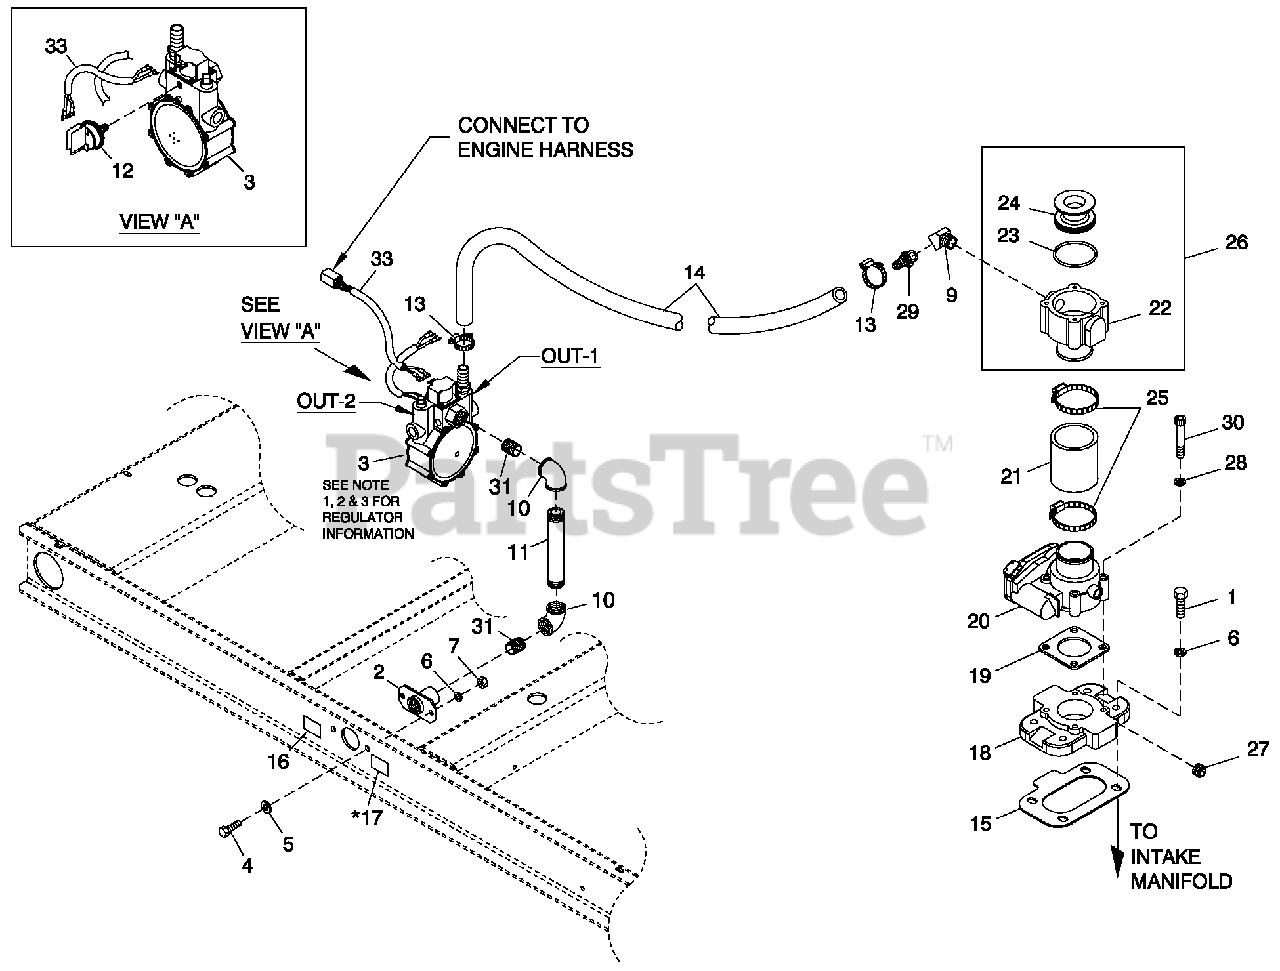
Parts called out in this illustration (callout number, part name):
1	SCREW HHC 5/16-18 X 1-1/4 G5
2	FLANGE FUEL INLET
3	REGULATOR ASSEMBLY DUAL FUEL
4	SCREW HHC M8-1.25 X 20 G8.8
5	WASHER FLAT 5/16-M8 ZINC
6	WASHER LOCK M8-5/16
7	NUT HEX M8-1.25 G8 CLEAR ZINC
9	STREET EL 45 DEG 1/2" NPT BRASS
10	ELBOW 90D 3/4 NPT
11	NIPPLE PIPE 3/4 NPT X 7”
12	SWITCH PRESSURE GAS 5" RISE (INCLUDED WITH I/N 3)
13	CLAMP HOSE #10 .56-1.06
14	HOSE 5/8 ID X 31.0" LG
15	GASKET CARB ADAPTOR
16	DECAL INLET PRESSURE
17	DECAL FUEL INLET NG (NATURAL GAS APPLICATION)
18	MACHINING, CARBURETOR ADAPTOR
19	GASKET BOSCH 32 & 40
20	ACTUATOR BOSCH 40, GOVERNOR
21	HOSE COOL 2IN ID 20R4 (2” LG)
22	VENTURI HOLDER W/40MM ACTUATOR
23	O-RING 47.625 ID X 2.38 WIDTH
24	VENTURI 28 ID THROTTLE W/CHOKE
25	CLAMP HOSE #36 1.88-2.75
26	ASSY THROTTLE 28MM
27	PLUG STD PIPE 1/8 SOCKET HEAD
28	WASHER LOCK M6-1/4
29	BARBED STR 1/2 NPT X 5/8
30	SCREW SHC M6-1.0 X 45 G12.9
31	NIPPLE CLOSE 3/4 X 1.375
33	HARNESS CPL FUEL JUMPER
